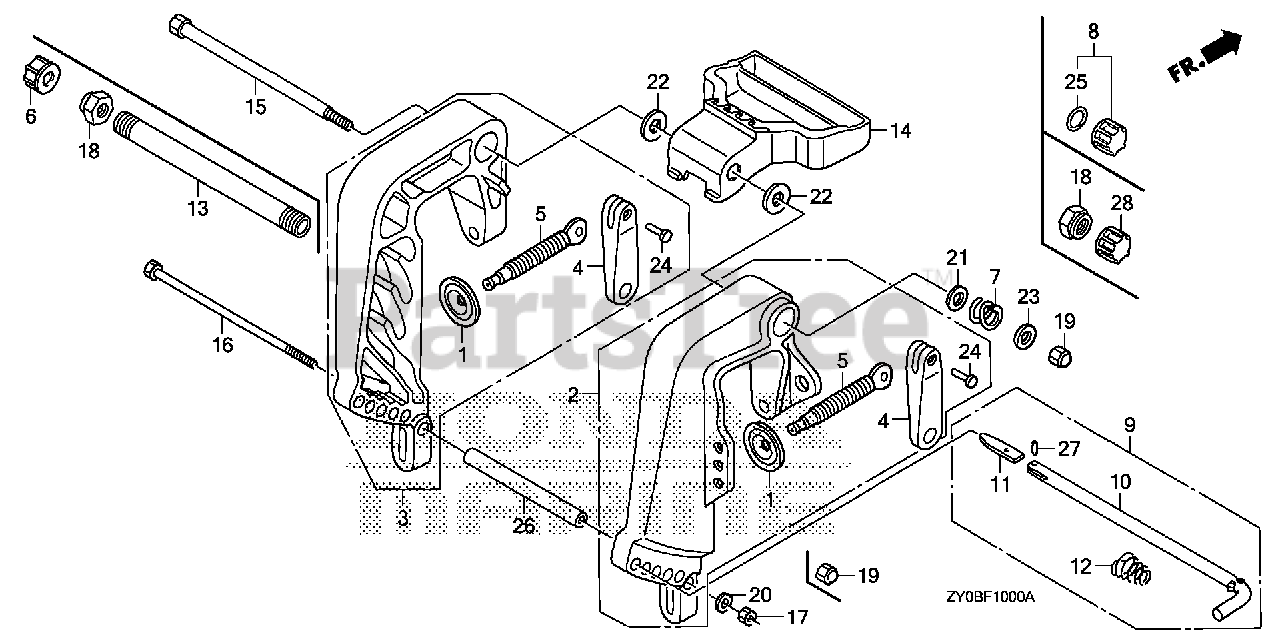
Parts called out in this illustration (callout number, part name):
1	PLATE, PUSH
2	BRACKET, R. STERN *NH282MU* (OYSTER SILVER METALLIC-U)
3	BRACKET, L. STERN *NH282MU* (OYSTER SILVER METALLIC-U)
4	GRIP, CLAMP
5	SCREW, CLAMP
7	SPRING, TILT
9	ROD, ADJUSTING
10	ROD, ADJUSTING
11	STOPPER, ROD
12	SPRING, ADJUSTING ROD
14	HANDLE, CARRYING
15	BOLT, TILTING
16	BOLT, HEX. (6X160)
17	NUT, HEX. (6MM)
19	NUT, SELF-LOCK (8MM)
20	WASHER, PLAIN (6MM)
21	WASHER, PLAIN (10MM)
22	WASHER (10MM)
23	WASHER (8MM)
24	RIVET (4X22.6)
26	COLLAR, DISTANCE (6MM)
27	PIN, SPRING (2X8)
